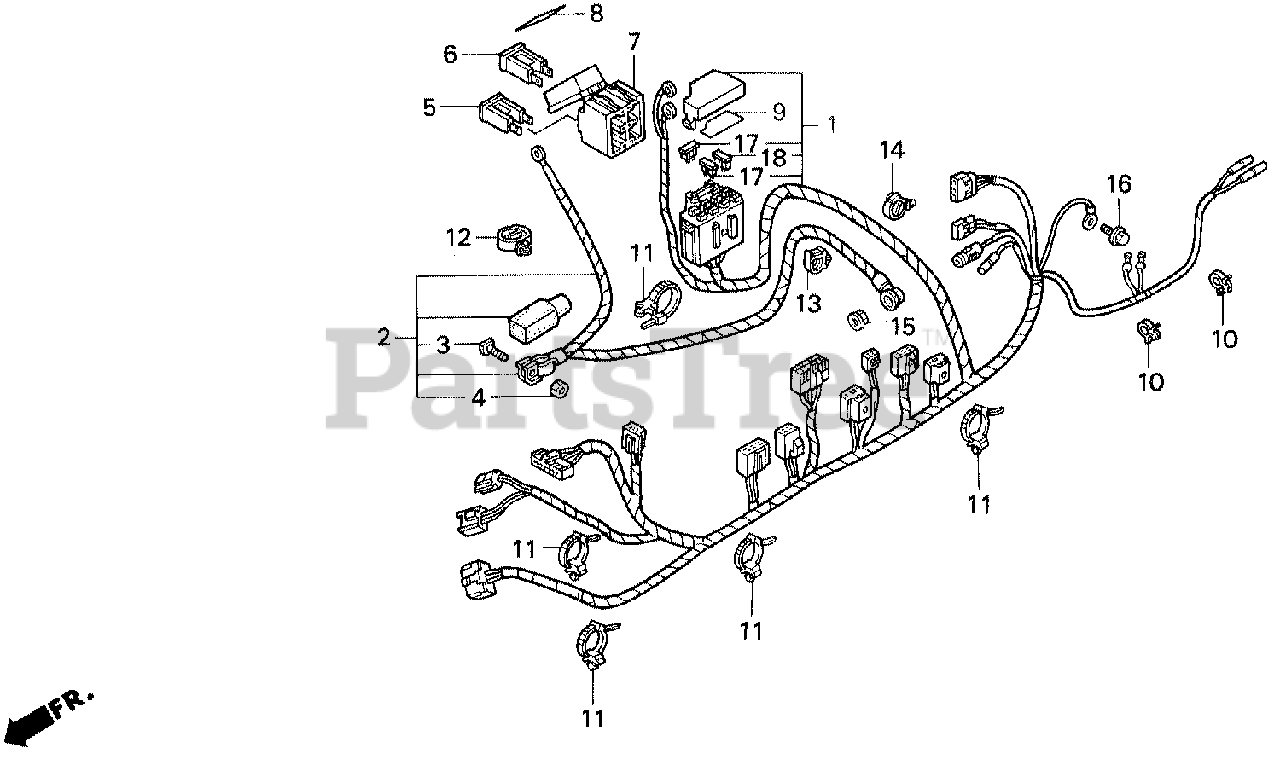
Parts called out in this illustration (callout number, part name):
1	WIRE HARNESS ASSY., MAIN
2	CABLE ASSY., STARTER
3	BOLT, BATTERY TERMINAL
4	NUT, BATTERY TERMINAL
5	FUSE, BLOCK (50A)
6	FUSE, BLOCK (70A)
7	CASE, MAIN FUSE
8	MARK, FUSE
9	MARK, BRANCH FUSE
10	CLIP, WIRE HARNESS (8MM) *NH1* (BLACK)
11	BAND, WIRE HARNESS (WHITE)
12	CLIP, WIRE HARNESS (25MM)
13	CLIP, WIRE HARNESS
14	STRAP, WIRE HARNESS (25MM) (BLACK)
15	NUT-WASHER (8MM)
16	BOLT, FLANGE (10X12)
17	FUSE, BLADE (5A)
18	FUSE, BLADE (10A)
